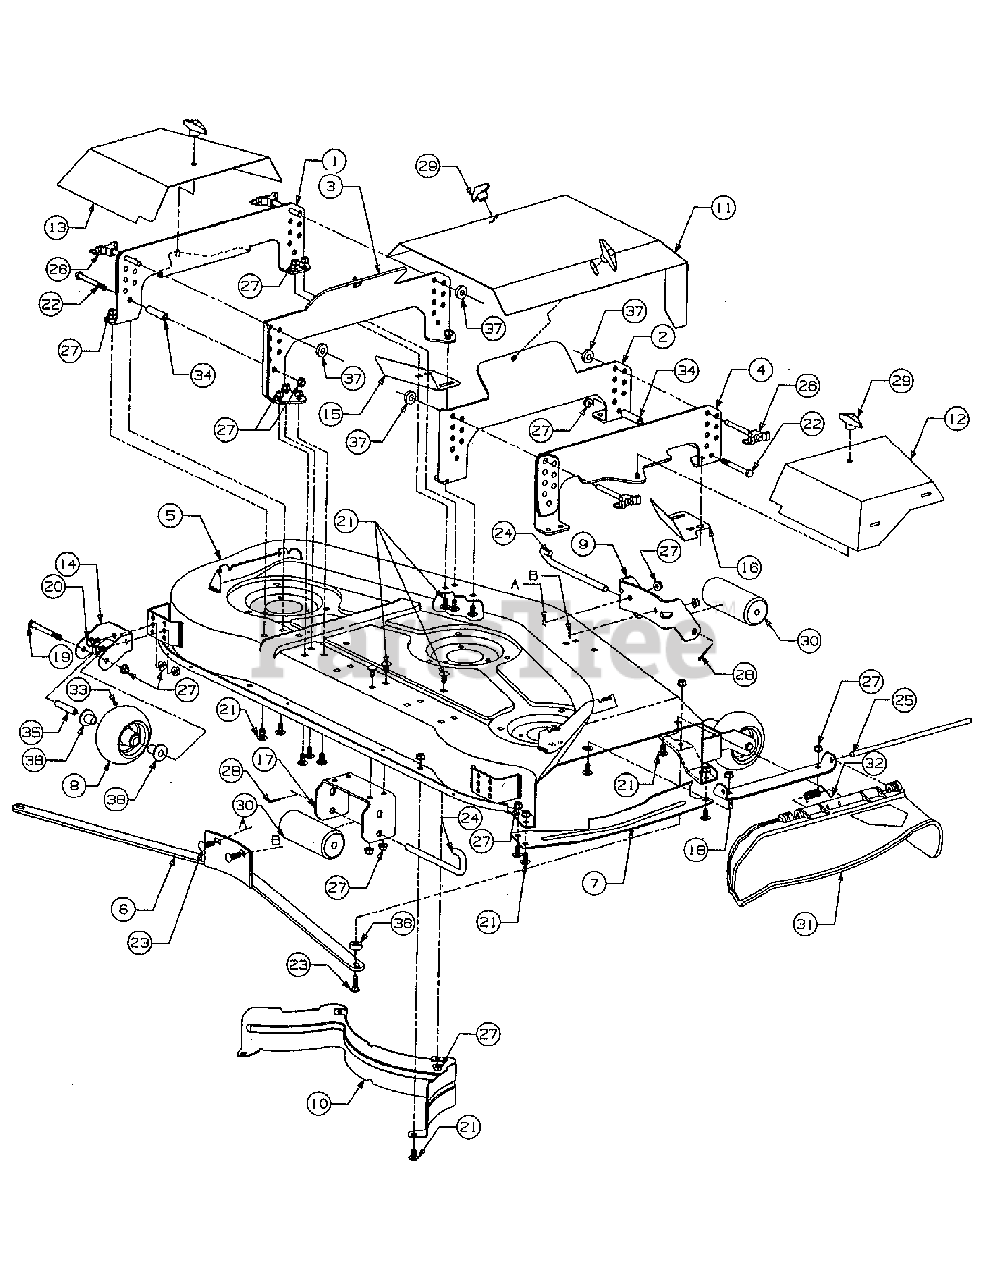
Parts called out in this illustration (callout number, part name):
4	Hanger, RH Outer
5	Housing Assembly, w/Graphics 54'' Mower
5	Graphic, Danger Cut Finger
5	Graphic, Danger
8	Wheel Assembly, 5'' Deck w/ Fitting
8	Wheel Assembly, Deck
10	Baffle, Rear Inner
11	Graphic, Belt Cover Front
11	Graphic, 5418F, Belt, Cover Right
16	Plate, RH Filler
19	Screw, Hex Cap, 3/8-16 x 3.75
19	Screw, Hex Cap, 3/8-16 x .88
20	Screw, Hex Wash Sf Tap, 3/8-16 x .75 Gr 5
21	Bolt, Sht Nk Carriage, 3/8-16 x .75 Gr 5
22	Screw, Hex Cap, 3/8-16 x 3.25 Gr 5
23	Bolt, Carriage, 3/8-16 x 1.25 Gr 5
24	Pin, Roller, 1/2 Dia x 7.31
25	Pin, Hinge, .375 Dia x 12.55
26	Pin, Quick Release, 3/8 Dia
27	Nut, Hex Flanged Lock 3/8-16
28	Pin, Cotter, 1/8 Dia x 1.0
29	Knob, Wing Nut
31	Deflector, Chute
31	Graphic, Danger Cut Finger
32	Spring, Torsion
33	Fitting, Lube
34	Spacer, Deck Hanger
35	Spacer, Deck Wheel
36	Spacer, Front Bar
37	Washer, Flat.385 x .870 x .092 Thk
38	Bearing, Flange
